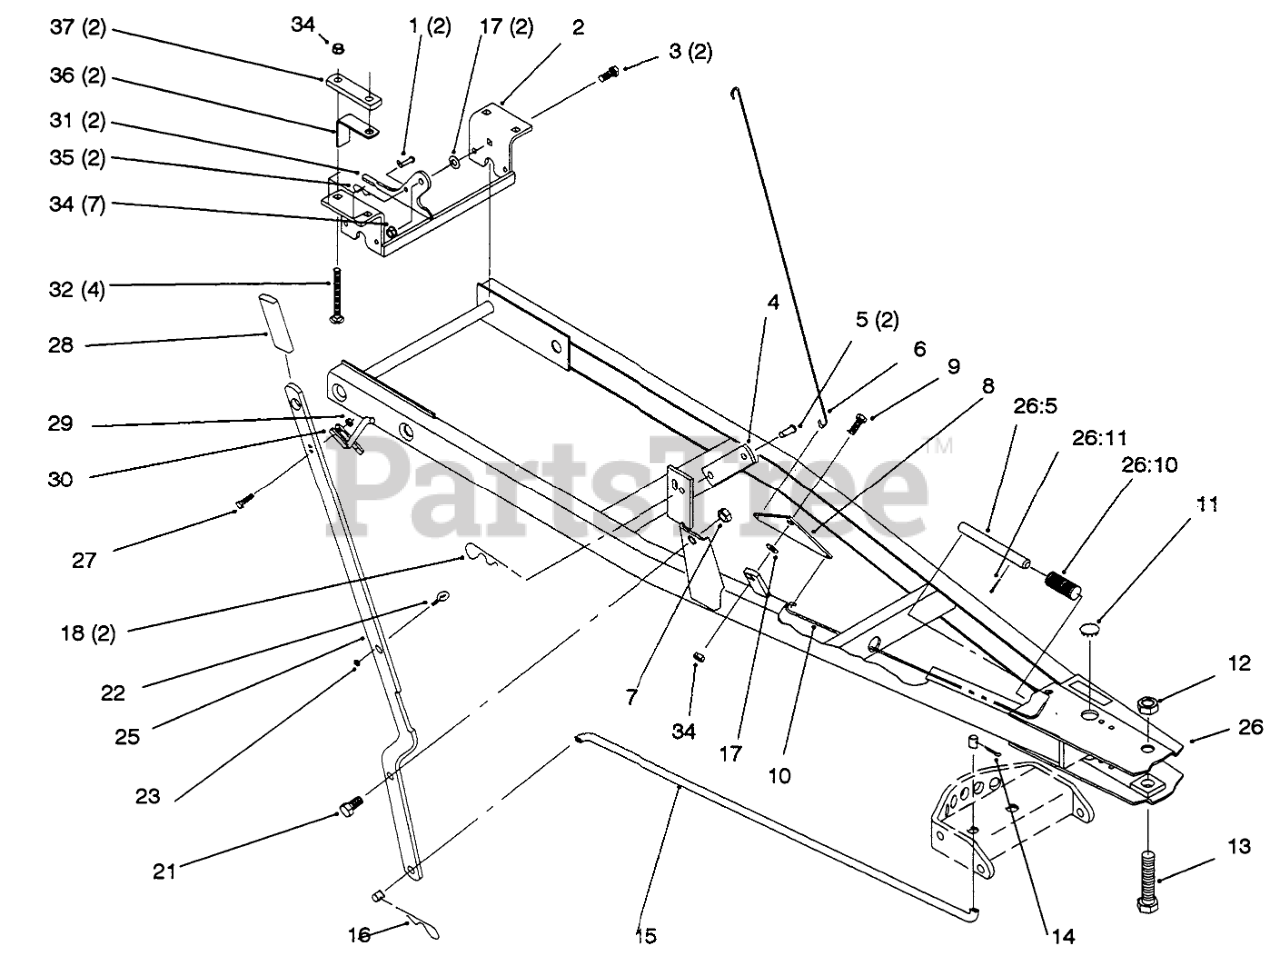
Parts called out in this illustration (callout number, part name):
1	Pin-Clevis
2	Bracket
3	BOLT-CARR
4	LINK-LIFT
5	CLEVIS PIN
6	UPPER INDEX ROD
7	NUT-JAM
8	PLATE - INDEX
9	SCREW-HH
10	Head-Cylinder
11	PLUG
12	NUT-LOCK
13	SCREW-HH
14	PIN-COTTER
16	PIN-HAIR
17	WASHER-FLAT
18	PIN-HAIR
21	SCREW-HH
22	EYEBOLT
23	NUT-LOCK, NI
25	Index Lever
26	ASSY-FRAME R
26:5	PIN-INDEX
26:10	SPRING-COMPRESSION
26:11	PIN-COTTER
27	SCREW-HH
28	GRIP
29	NUT-LOCK
30	INDEX LEVER
31	PLATE-LATCHING
32	SCREW-CARR
34	NUT-LOCK, NI
35	PIN-HAIR
36	SPACER-BRACKET
37	BRACKET-REAR LINK MOUNTING
